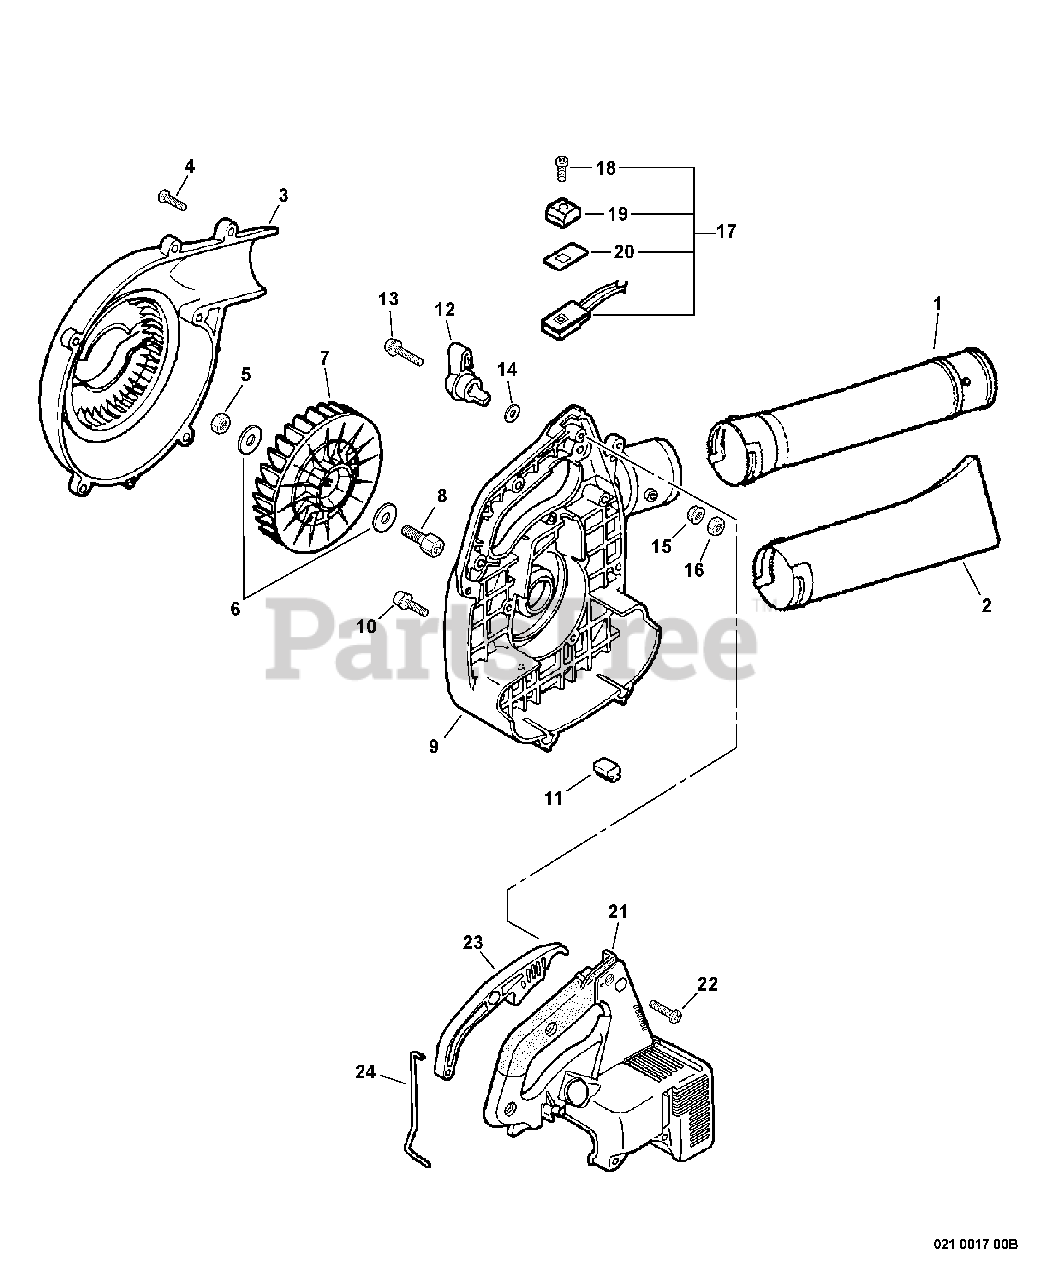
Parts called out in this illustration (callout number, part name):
1	TUBE, BLOWER - STRAIGHT
2	TUBE, BLOWER - NOZZLE
3	COVER, FAN
4	SCREW, TAPPING 5×20
8	HUB, FAN
9	COVER, FAN - OUTER
10	SCREW 4×22
12	CONTROL, THROTTLE
13	SCREW 5×25
14	WASHER 5.5×12×0.8
15	NUT, FLANGE M5
17	CABLE ASSY, CONTROL
18	SCREW 3×10
19	KNOB, SWITCH - ORANGE
20	LABEL, SWITCH
21	COVER, ENGINE
22	SCREW, TAPPING 5×20
23	CONTROL, THROTTLE
24	ROD, THROTTLE
